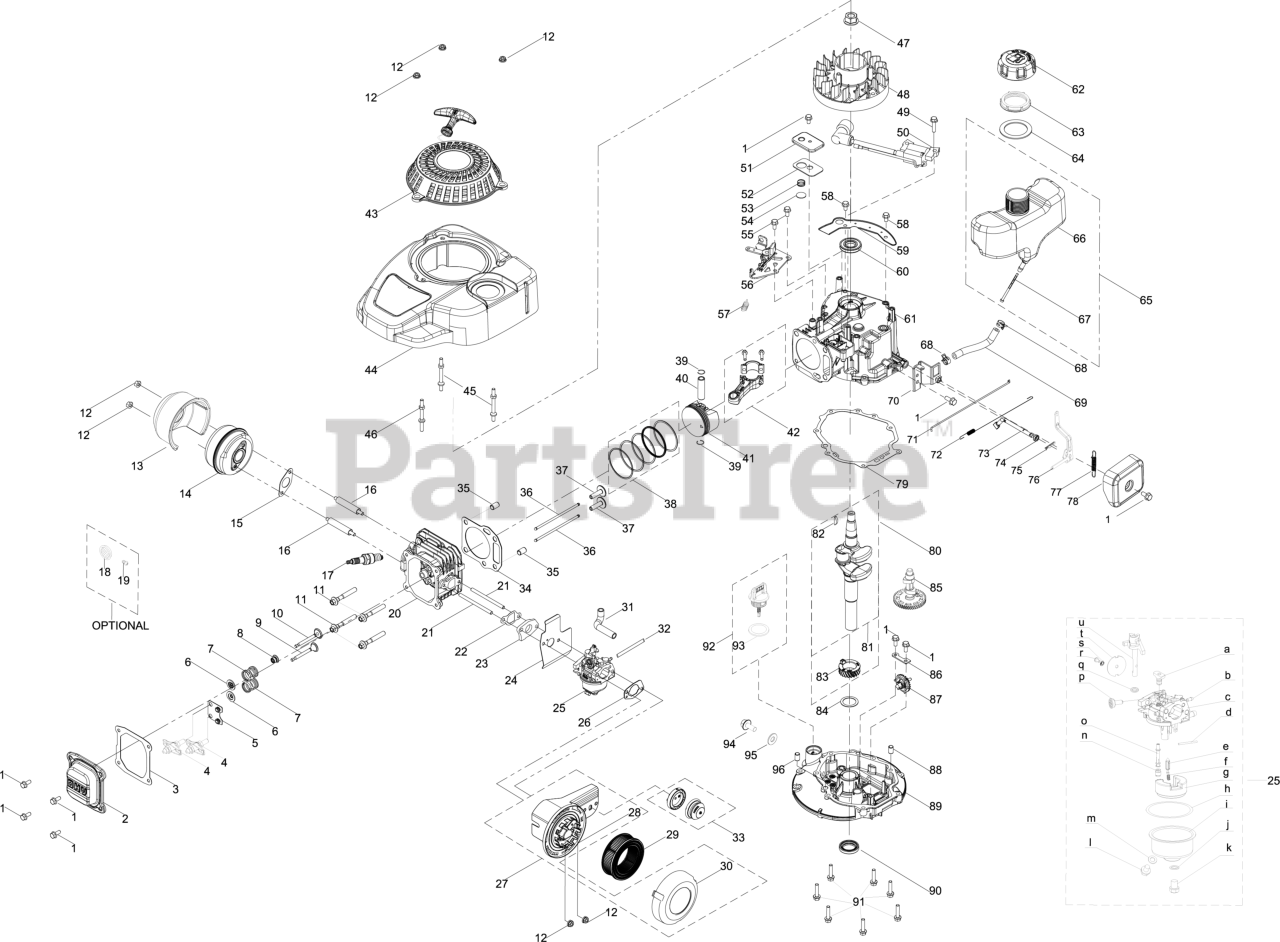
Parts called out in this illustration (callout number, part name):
1	BOLT M6-1 x 14 GR8.8
2	VALVE COVER
3	VALVE COVER GASKET
5	PUSH ROD GUIDE
6	VALVE RETURN SPRING
7	VALVE SPRING
8	INTAKE VALVE SEAL
9	EXHAUST VALVE
10	INTAKE VALVE
11	SCREW M8 x 54 GR10
13	MUFFLER SHIELD
14	MUFFLER ASSEMBLY
15	MUFFLER GASKET
16	STUD M6-1 x 76
17	SPARK PLUG (F5RTC/RN11YC4/BPR5ES)
17	Cub Cadet SPARK PLUG-F5RTC
17	Genuine Factory Parts SPARK PLUG (14437)
18	SPARK ARRESTOR
19	SCREW M3.5 x 9.5
20	CYLINDER HEAD
21	STUD M6 x 98
22	CARBURETOR INSULATOR GASKET
23	CARBURETOR INSULATOR
24	CARBURETOR GASKET
25	CARBURETOR
26	AIR FILTER BASE GASKET
27	AIR FILTER ASSEMBLY
28	AIR FILTER BASE
29	PAPER AIR FILTER
30	AIR FILTER COVER
31	BREATHER HOSE
32	PRIMER HOSE
33	VENTED PRIMER ASSEMBLY
34	CYLINDER HEAD GASKET
35	PIN (10MMx16MM)
38	PISTON RING SET
39	WRIST PIN CLIP
42	CONNECTING ROD ASSEMBLY
43	STARTER RECOIL ASSEMBLY
44	ENGINE SHROUD ASSEMBLY
45	STUD M6 x 75
46	STUD M6 x 73
47	FLYWHEEL NUT M14-1.5
48	FLYWHEEL
49	BOLT M6-1 x 25 GR8.8
50	IGNITION COIL ASSEMBLY
51	BREATHER COVER PLATE
52	BREATHER COVER GASKET
53	BREATHER VALVE SPRING
54	BREATHER VALVE
55	BOLT M6-1 x 12 GR8.8
56	ENGINE BRAKE ASSEMBLY
57	BRAKE SPRING
58	BOLT M6-1 x 10 GR8.8
59	SHROUD COVER PLATE
62	FUEL CAP ASSEMBLY
63	FUEL TANK NUT
64	FUEL TANK GROMMET
67	FUEL FILTER
68	CARBURETOR HOSE CLAMP
70	COMPONENT BRACKET
71	THROTTLE LINKAGE
72	THROTTLE LINKAGE SPRING
73	GOVERNOR ARM SHAFT
76	GOVERNOR ARM ASSEMBLY
77	GOVERNOR SPRING
78	GOVERNOR SHIELD
79	CRANKCASE COVER GASKET
81	CRANKSHAFT
82	WOODRUFF KEY
84	THRUST WASHER
85	CAMSHAFT
86	GOVERNOR GEAR MOUNTING PLATE
87	GOVERNOR GEAR/SHAFT ASSEMBLY
88	DOWEL PIN 7 X 14
89	CRANKCASE COVER
90	LOWER CRANKSHAFT SEAL
91	BOLT-M6-1 x 28 GR8.8
92	DIPSTICK ASSEMBLY
93	DIPSTICK O-RING
94	OIL DRAIN PLUG
95	FLAT WASHER
96	DOWEL PIN 9 X 14
